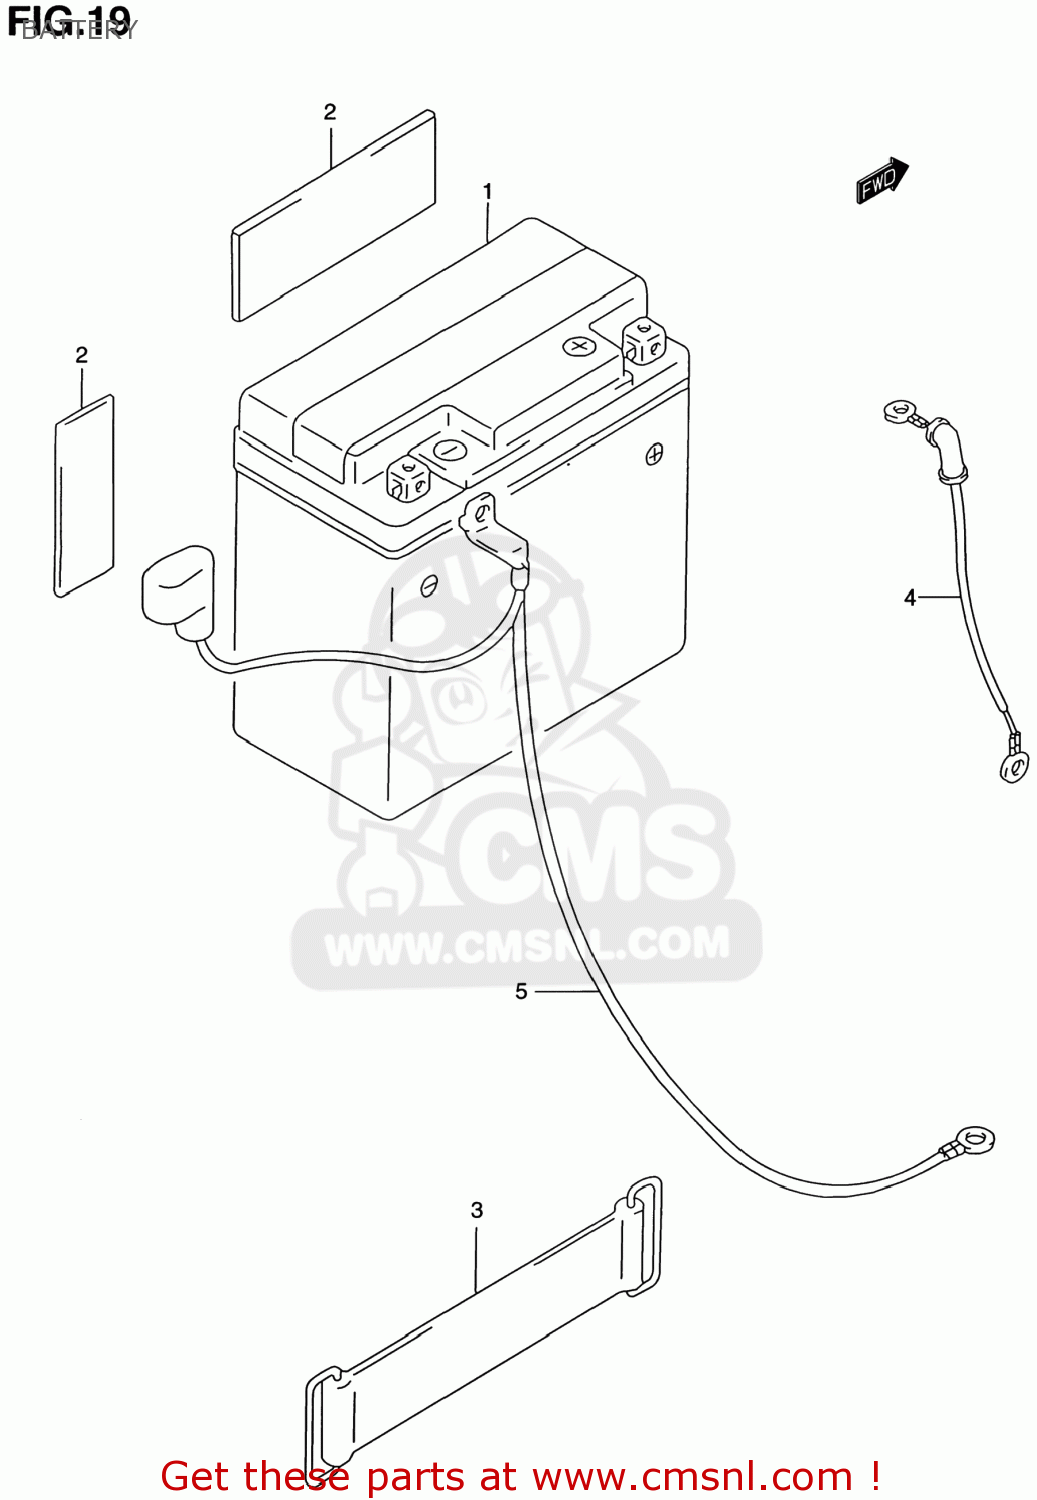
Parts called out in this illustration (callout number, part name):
1	BATTERY ASSEMBLY (12V) FTX
2	PROTECTOR(170X95X3.0)
3	BAND
4	WIRE,BATTERY PLUS LEAD
5	WIRE,BATTERY MINUS
